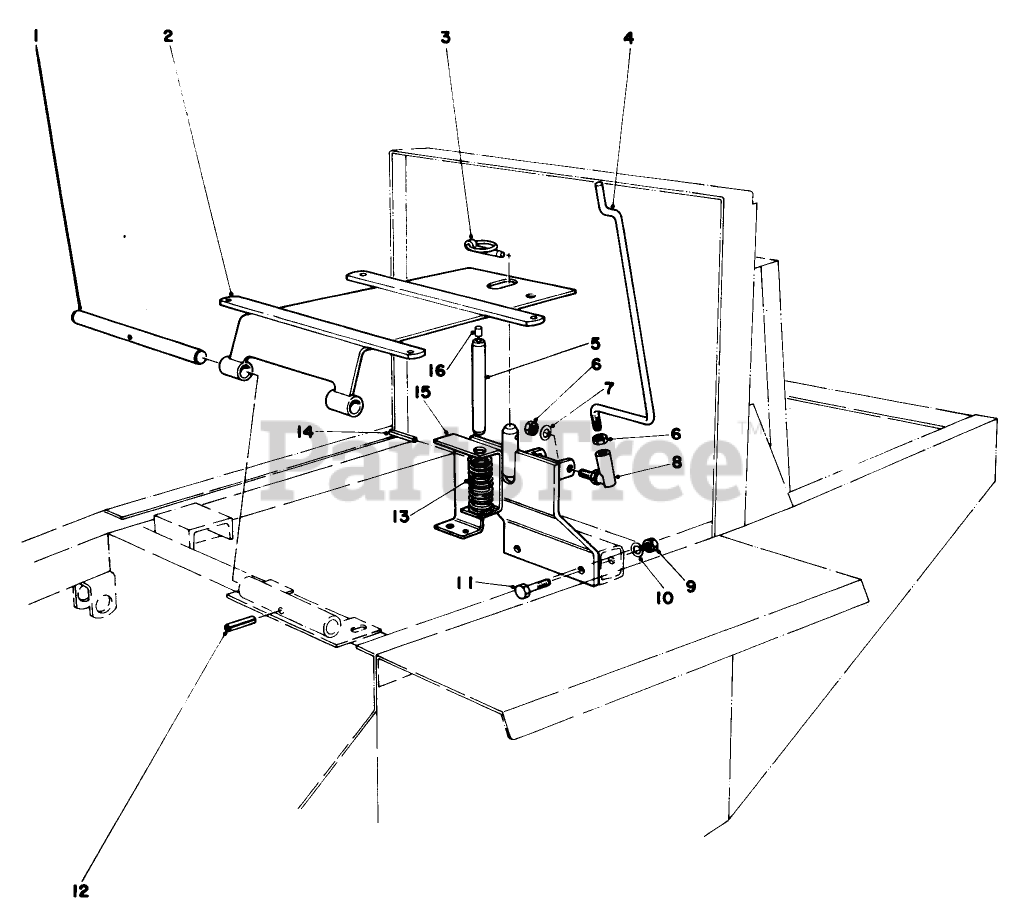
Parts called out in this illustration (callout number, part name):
1	SHAFT-PIVOT, SEAT
2	SEAT SUPT WA R
3	PIN-LYNCH
4	PROP SEAT
5	PIN-SWITCH, SEAT
6	NUT-JAM
7	WASHER-LOCK/SP
8	Ball Joint
9	NUT-HEX
10	WASHER-LOCK
11	SCREW-HH
12	PIN-ROLL, SLOTTED
13	SPRING-COMPRESSION
14	PIN-ROLL, SLOTTED
15	Bracket-Seat Support
16	PIN-PEDAL
